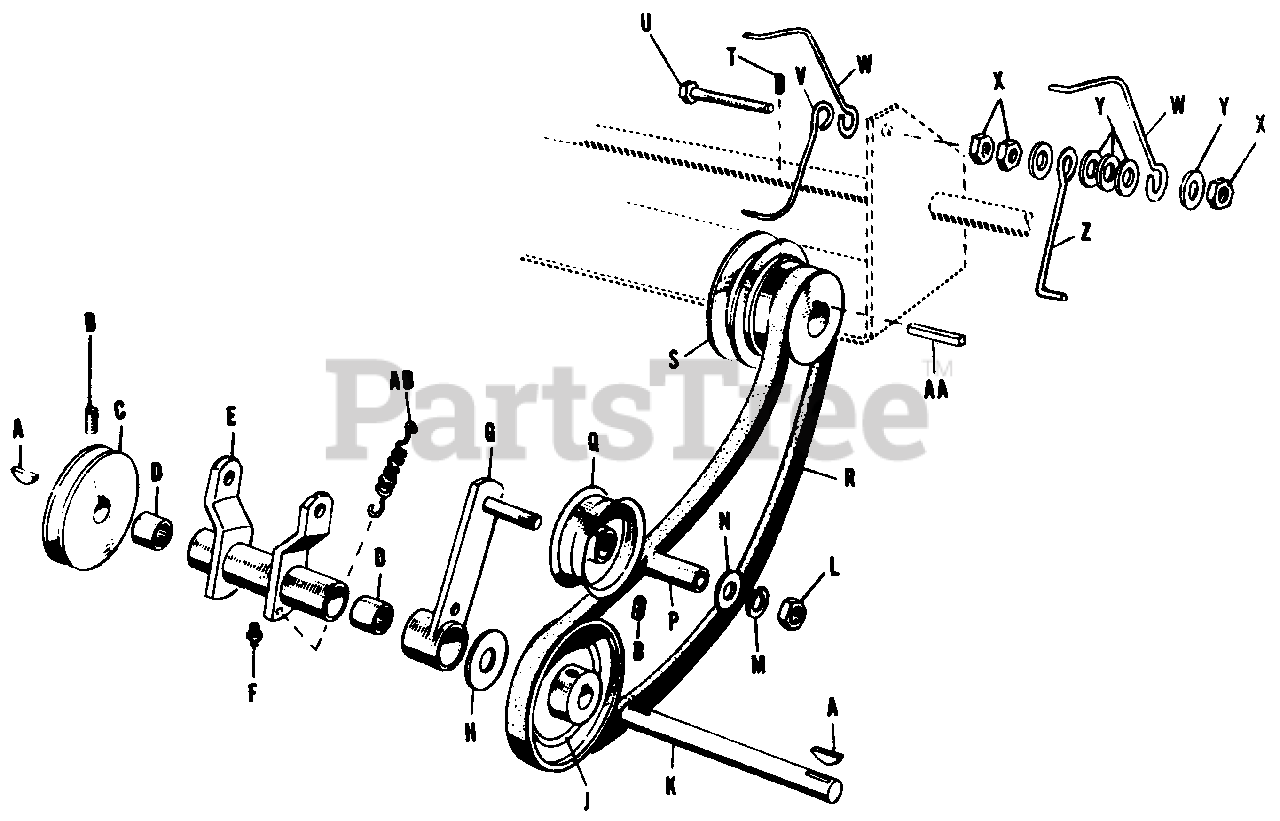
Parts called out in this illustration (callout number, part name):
A	Key, Woodruff, 3/16 x 3/4"
B	Screw, Set 5/16-18 x 1/2
D	Bearing, Needle
E	Bracket Assembly, Drive
F	Grease Writting No. 1641
G	Lever, Idler Assembly
K	Shaft, Idler
L	Nut, Full Hex, 3/8-16
M	Washer Lock, 3/8"
N	Washer Plain 3/8"
P	Race, Inner Bearing
Q	Pulley Idler
R	V-Belt 34" Long
S	Pulley, Englne
T	Screw, Set Cup Point 5/16-18 x 5/16"
U	Screw, Hex Hd. 3/8-16x2 1/2" (2 1/4" ThreadHOSE, Fuel, Cut to 12th)
V	Stop Belt
W	Stop Belt
X	Nut, Full Hex 3/8-16
Y	Washer, 5/16
Z	Stop, Belt
AA	Key, Engine
